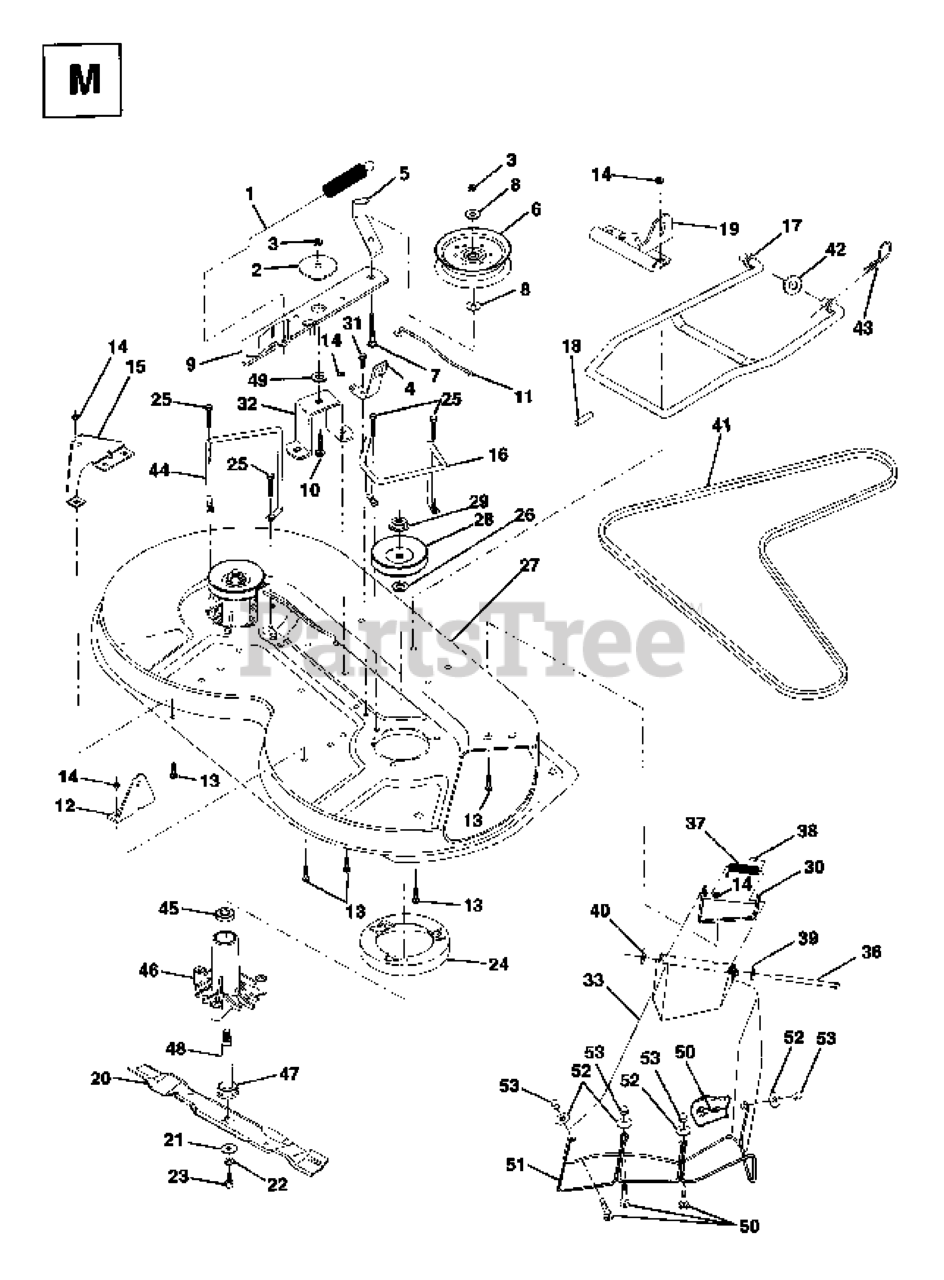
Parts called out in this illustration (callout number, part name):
1	SPRING-MOWER CLUTCH
2	SPACER RETAINER
4	BRAKE ASSEMBLY
5	IDLER BELT GUIDE
6	PULLEY.IDLER.FLAT.MOWER.BLK.PT
8	WASHER
9	IDLER ARM ASSY
10	BOLT.3/8-14X1.25
12	BRKT LIFT REAR
13	RP BOLT 5/16-18 X3/4 ZN/YEL GR
14	LOCKNUT
15	BRKT LIFT REAR LH
16	KEEPER RH
17	MOWER LINK STABILIZER
18	PIN GROOVE
19	BRKT LINK STABILIIZER
20	BLADE, HI-LIFT 36" PREMIUM
21	WASHER.BLADE
22	LOCKWASHER
23	BLADE BOLT
24	STRIPPER
25	SCREW
26	WASHER
27	MOWER HOUSING
28	PULLEY
29	NUT
30	BRACKET ASM DEFLECTOR
31	Screw 5/16-18 x 1/2 Hex, Self Tapping 5/16-18 x 1/2
32	SUPT,IDLER ARM
33	DEFLECTOR
36	HINGE ROD
37	SPRING TORSION
38	CAP-SLEEVE LT
39	Washer 11/32 x 5/8 x 16 Ga SD
40	NUT PUSH M
42	WASHER
43	SPRING RETAINER
46	HOUSING.MANDREL.VENTED (MACHD)
47	BEARING.BALL.#6204.(MANDREL)
48	SHAFT ASM VENT
49	HARDENED WASHER
52	WASHER
